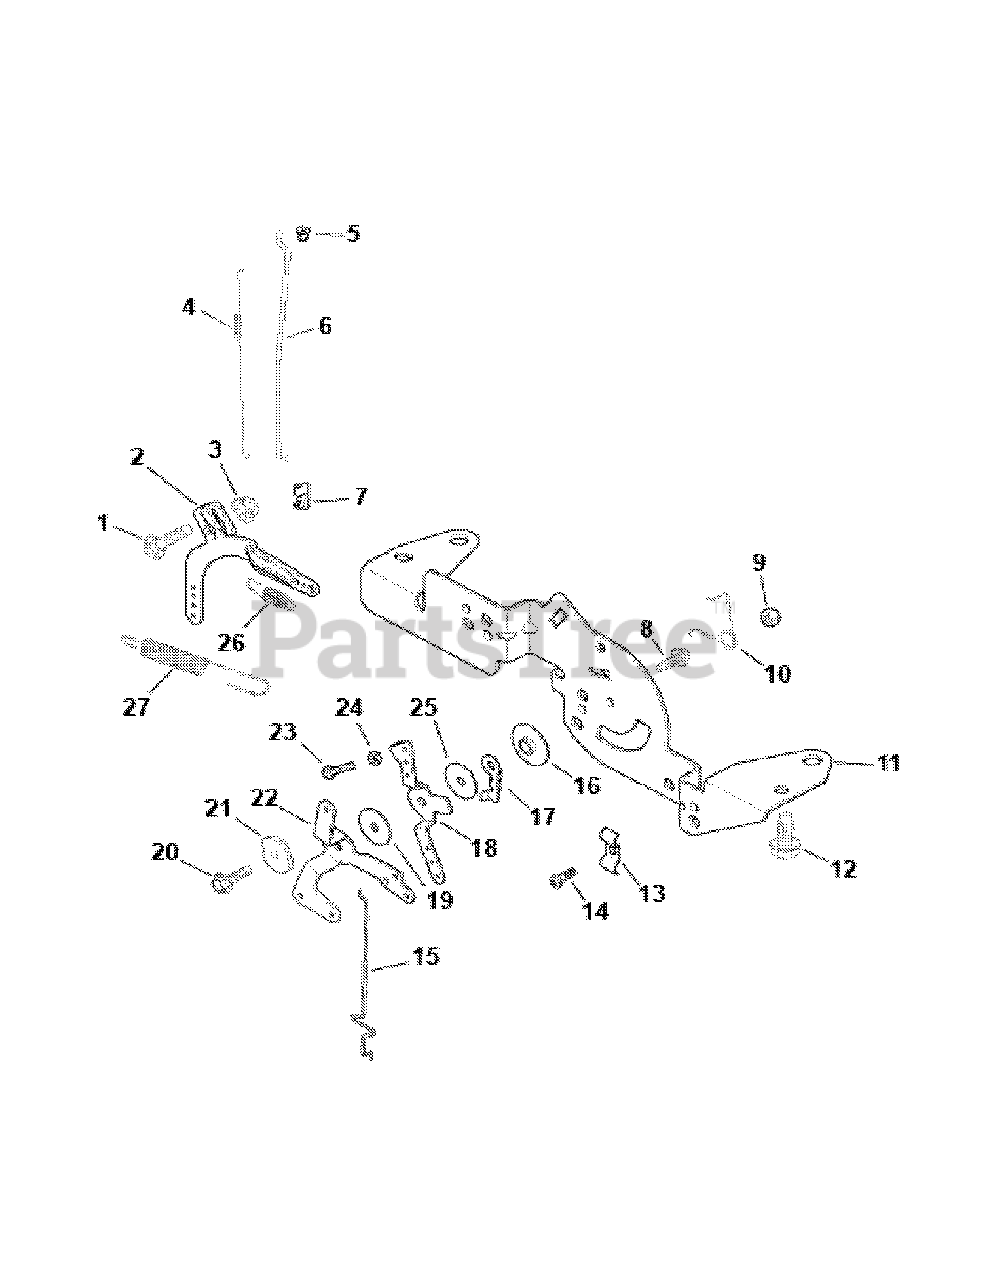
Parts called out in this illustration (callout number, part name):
1	Round Head Square Neck Bolt
2	Governor Lever
3	Hex Flange Nut
4	Linkage Spring
5	Linkage Retaining Bushing
6	Throttle Linkage
7	Throttle Linkage Bushing
8	Hex Flange Screw
10	Choke Return Spring
11	Control Bracket
12	Hex Flange Screw
13	Dual Conduit Clamp
14	Thread Forming Screw
15	Choke Linkage
16	Control Assembly Spacer
17	Throttle Actuator Lever
18	Throttle Control Lever
19	Plain Washer 5.5mm
20	Hex Flange Screw
21	Spring Washer 1/4"
23	Hex Head Cap Screw
26	Governor Spring
27	Governor Spring
